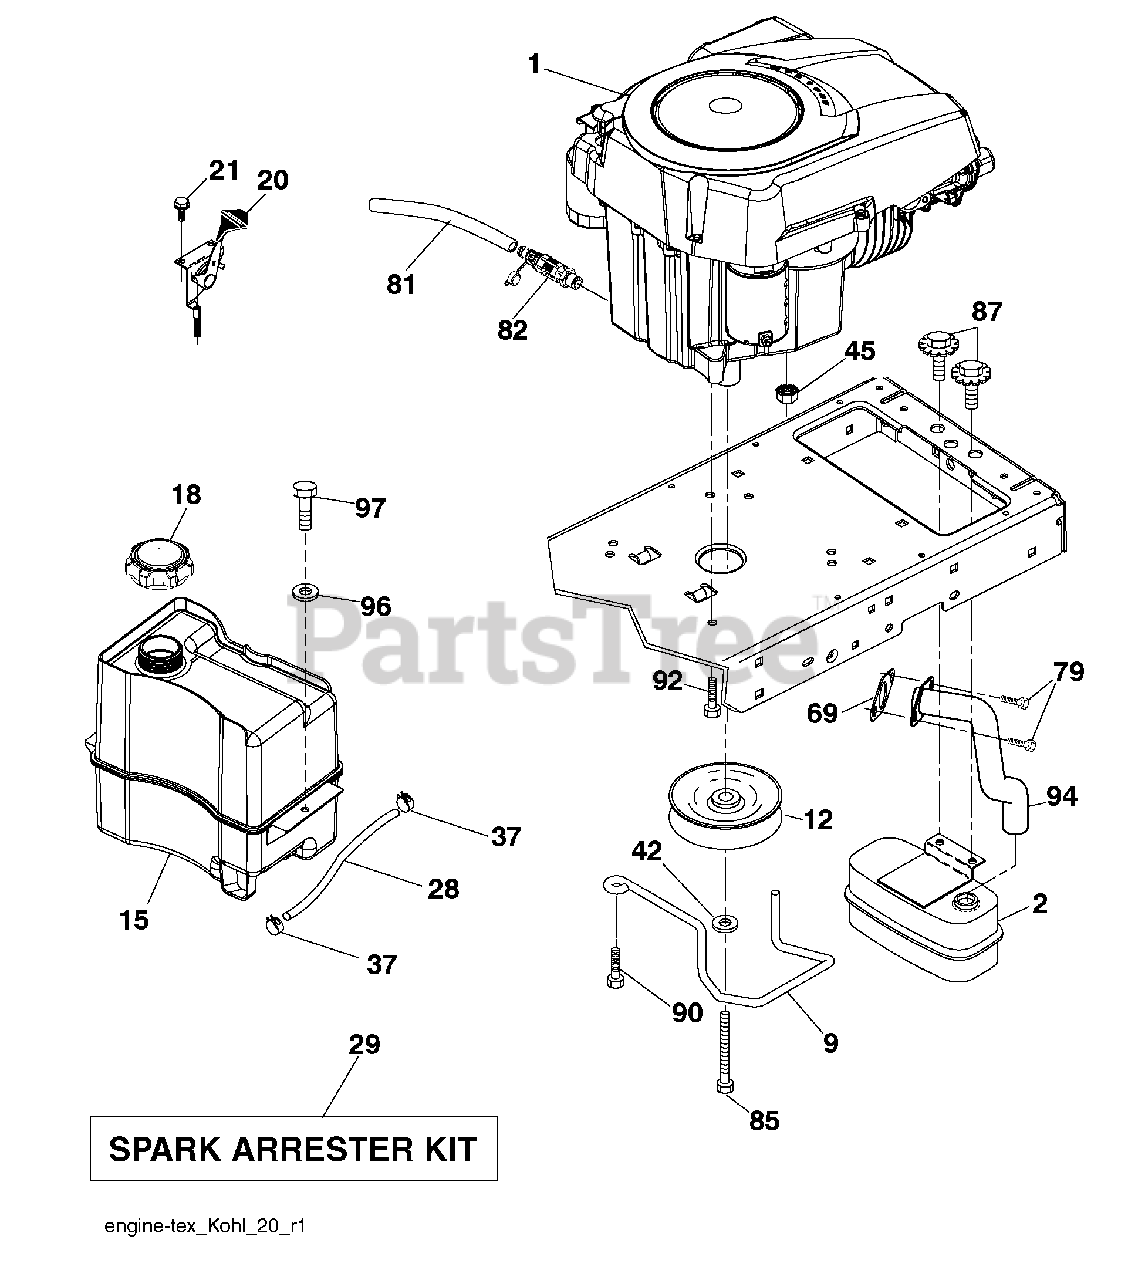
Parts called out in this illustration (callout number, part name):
9	Keeper Belt Engine
12	Pulley Engine
15	Tank Fuel
18	Cap Asm
20	Control Throttle/Choke
21	Screw #10 X 0.750 Bos Thread
28	Fuel Line
29	Spark Arrester Kit
37	Clamp Hose
42	Washer Lock 7/16
45	Nut Keps Hex 1/4-20 Unc
79	Screw Socket Head
81	Tube Drain Oil Easy
82	Valve Drain Oil
85	Bolt Hex 7/16-20 X 4 X Gr. 5-1.5 Thr
87	Bolt 5/16-18 Unc X 3/4 W/Sems
90	Screw 3/8-16 X 1
92	Screw 3/8-16 X 1
94	Tube Exhaust
96	Washer 9/32 X 7/8 X 16 Ga.
97	Screw Hexwsh Thdrol 1/4-20 X 3/4
